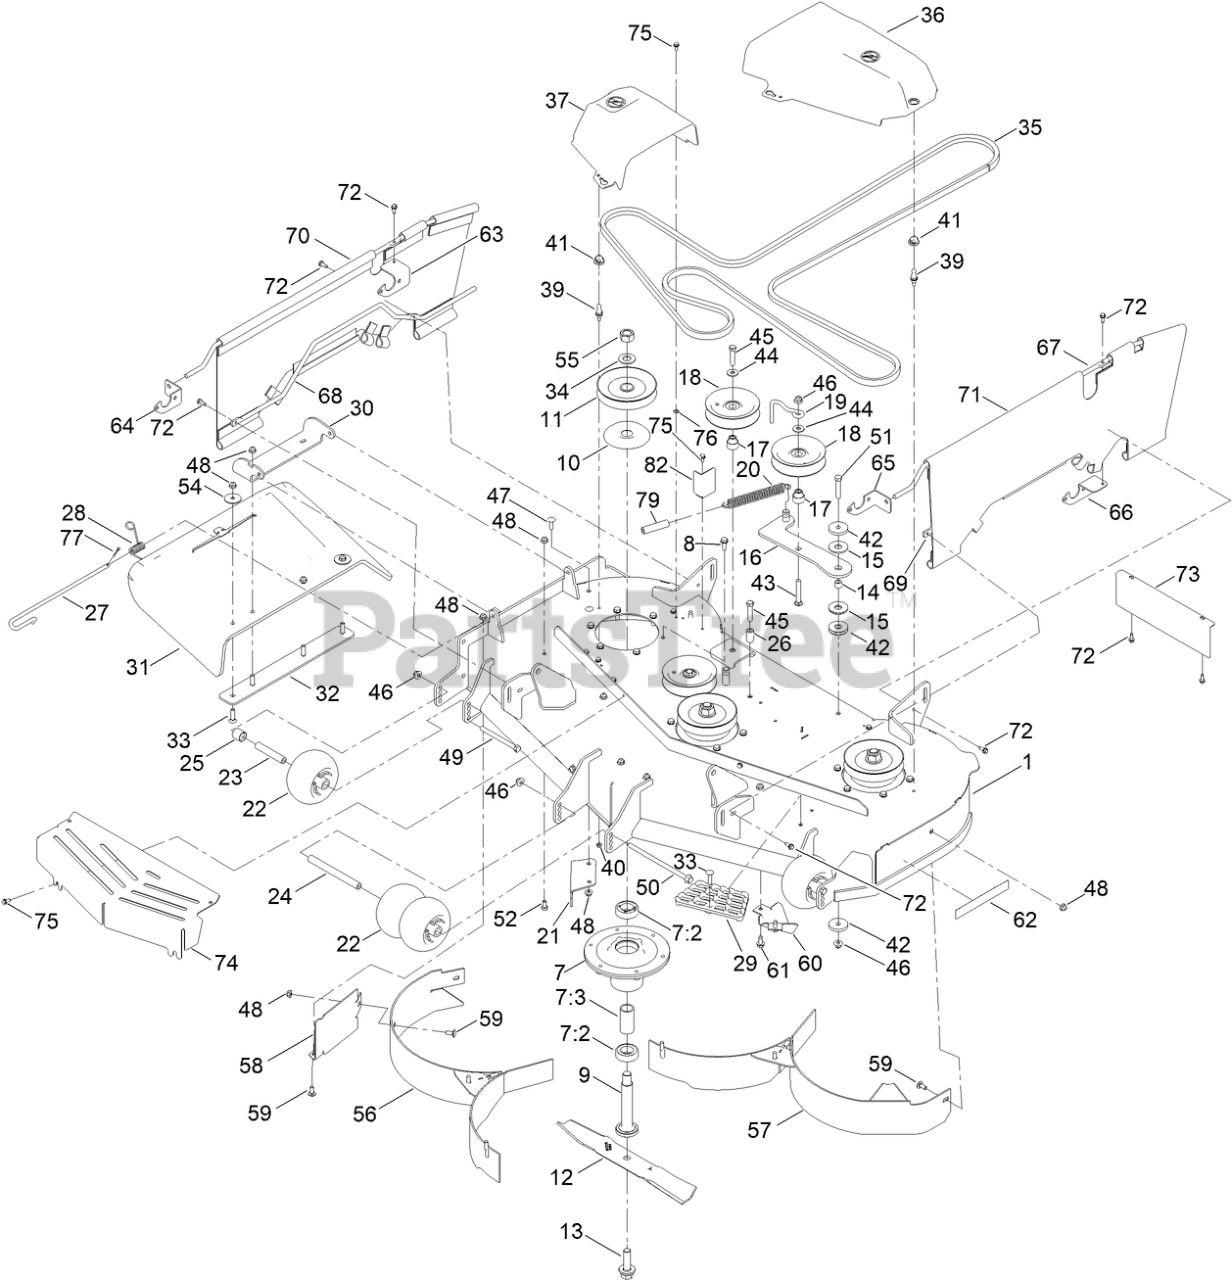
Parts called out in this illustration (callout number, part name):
1	48 IN DECK DECAL ASM
7	SPINDLE ASM
7:2	BEARING-BALL
7:3	SPACER-BEARING
8	SCREW-TAPTITE
9	SHAFT-SPINDLE
10	SHIELD-BEARING
11	PULLEY
12	BLADE-MULCH, 16.50 INCH
13	SCREW-BLADE
14	SPACER
15	WASHER-FRICTION, COMPOSITE
16	IDLER ARM ASM
17	BUSHING-IDLER
18	PULLEY-IDLER, FLAT
19	GUIDE-BELT, IDLER
20	SPRING-EXTENSION
21	BAFFLE-CUTOFF
22	ROLLER-SCALP, ANTI
23	TUBE-SPANNER
24	SPACER-WHEEL
25	SPACER-AXLE, REAR
26	SPACER-FENDER
27	PIN-CHUTE
28	SPRING-TORSION
29	STEP-DECK
30	BRACKET-DEFLECTOR, UPPER
31	DEFLECTOR - MOLDED
32	PLATE-DEFLECTOR
33	BOLT-CARRIAGE
34	WASHER
35	V-BELT
36	COVER-BELT, LH
37	COVER-BELT, RH
39	STUD-BALL
40	NUT-LOCK
41	GROMMET-BALL
42	WASHER-PLAIN
43	SCREW-CARR
44	WASHER-HARDENED
45	SCREW-HH
46	NUT-HF, NI
47	SCREW-CARR
48	NUT-HF
49	SCREW-HH
50	SCREW-HF
51	HHCS 3/8-16 X 2, GR5, CZ
52	SCREW-HH
54	WASHER-FLAT
55	NUT-HEX
56	BAFFLE-RECYCLER
57	BAFFLE-RECYCLER
58	GUARD-BAFFLE
59	BOLT-CARR
60	KICKER-FLANGED
61	SCREW-HWHTF
62	DECAL-RECYCLER
63	BRACKET-FRENCH GUARD
64	BRACKET-FRENCH GUARD
65	BRACKET-FRENCH GUARD
66	BRACKET-FRENCH GUARD
67	ROD-FRENCH GUARD
68	ROD-FRENCH GUARD
69	ROD-FRENCH GUARD
70	GUARD ASM-SIDE, POLY KNIT
71	GUARD ASM-SIDE, POLY KNIT
72	SCREW-HWH
73	PLATE-GUARD REAR
74	BRKT-SHIELD, FRONT
75	SCREW-HWH
76	NUT-RETAINING
77	PIN-COTTER
79	HOSE-BREATHER
82	BRACKET-GUARD, CE
